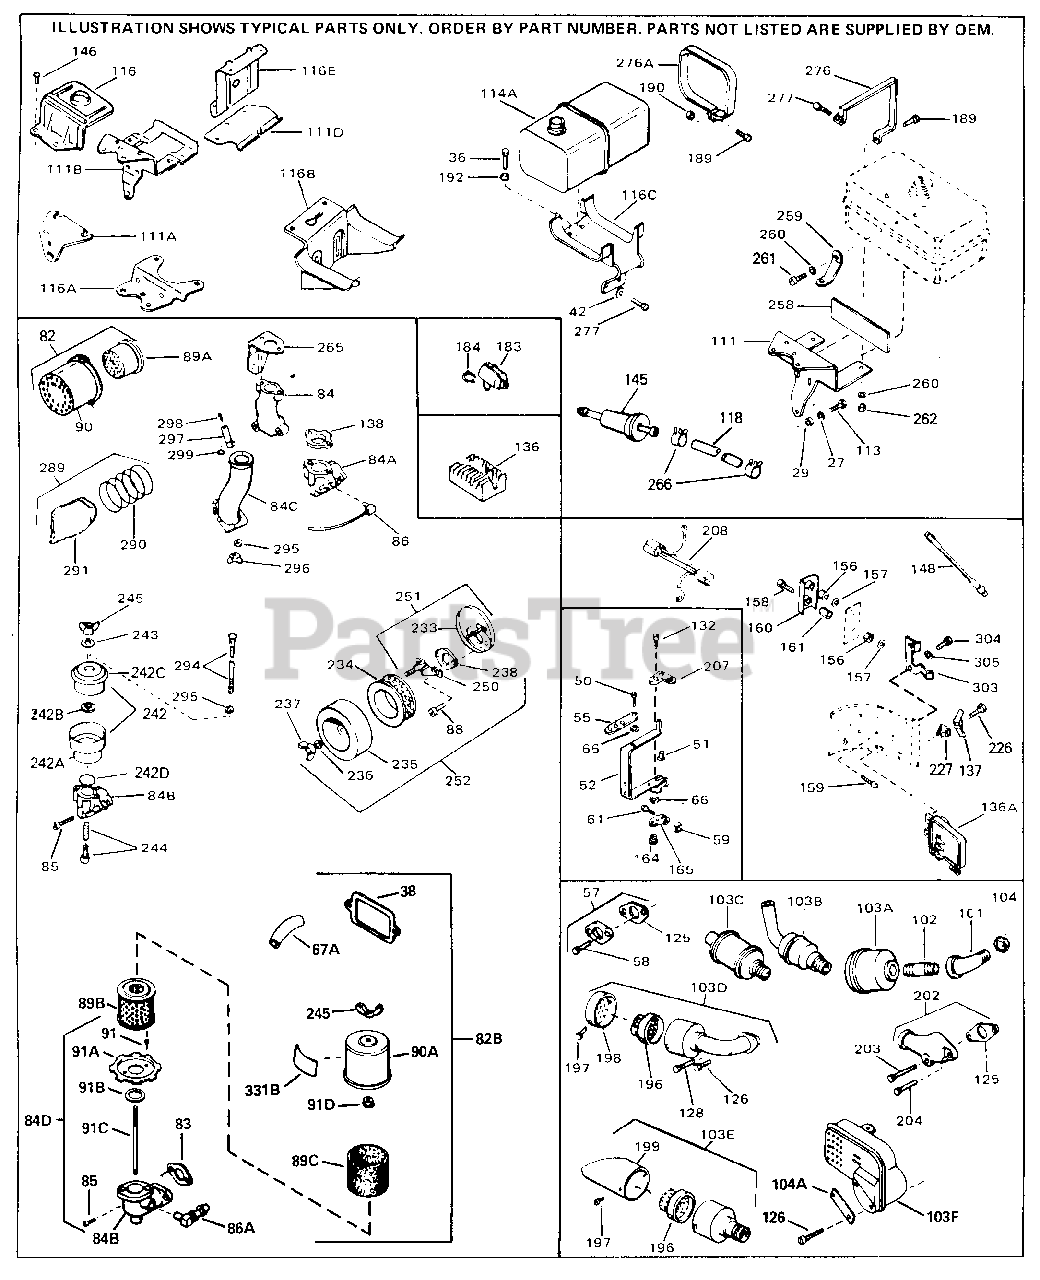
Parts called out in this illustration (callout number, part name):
36	Screw, 5/16-18 x 2" (Use as required)
36	Screw, 5/16-18 x 2-1/4" Use as requir ed
36	Screw, 5/16-18 x 2-1/2" Use as requir ed
38	* Gasket, Breather cover
42	Washer, Flat (Use as required)
50	Screw, 8-32 x 5/16"
51	Rivet, Split Used in early production
52	Lever, Governor New lever does not ne ed 1 of 51,66,132,164,165,207
55	Bracket, Adjusting
57	Exh.Adap.Kit (Incl. 58 & 125) Use as req.
58	Screw, 5/16-18 x 3/4"
59	Lock Nut, 10-32
61	Screw, 10-32 x 3/4"
66	Lock Washer #8
82	Air Cleaner Ass'y. (Incl. 60, 83, 87, 88, 89A, 90, 238 & 331B) (Use as req uired)
82B	Air cleaner kit (Incl. 38, 67A, 83, 8 4B, 85,89B, 89C, 90A, 91, 91A, 91B, 9 1C, 91D, 245 & 331B) (Use only on eng ines with an externally vented fully adjustable carburetor)
83	* Gasket, Air cleaner
84	Elbow, Air cleaner
84D	Air Cleaner Elbow (Incl. 84B, 86A, 91 , 91A, 91B & 91C) (Use in 730561 asse mbly only)
88	Screw, 10-32 x 1/2"
90	Body, Air cleaner
101	Muffler Elbow
102	Muffler Nipple
103A	Muffler
103E	Opt. Spark Arrest Muffler Incl. 196,1 97,199
104	Conduit Nut
113	Screw, T-30, 1/4-20 x 1/2"
118	Fuel Line (8.62") as req.)
118	Fuel Line (Braided 16") (41 cm) Use a s req.
118	Fuel Line (Braided 32") (81 cm) Use a s req.
128	Screw, 5/16-18 x 2" (Use as required)
132	Screw, 8-32 x 5/16" Early production
148	Wire Assy., Alternator adapter 4-1/4 "
148	Wire Assy., Alternator adapter 6-3/4 "
202	Exh. Adaptor Kit (Incl. 125,203,204) As req.
203	Screw, 5/16-18 x 2-1/2" Use as requir ed
204	Screw, 5/16-18 x 1-1/2" Use as requir ed
266	Fuel Line Clamp
289	Kit. Pre-cleaner (Incl 290 & 291)
290	Spring, Pre-cleaner bag
291	Air Filter
